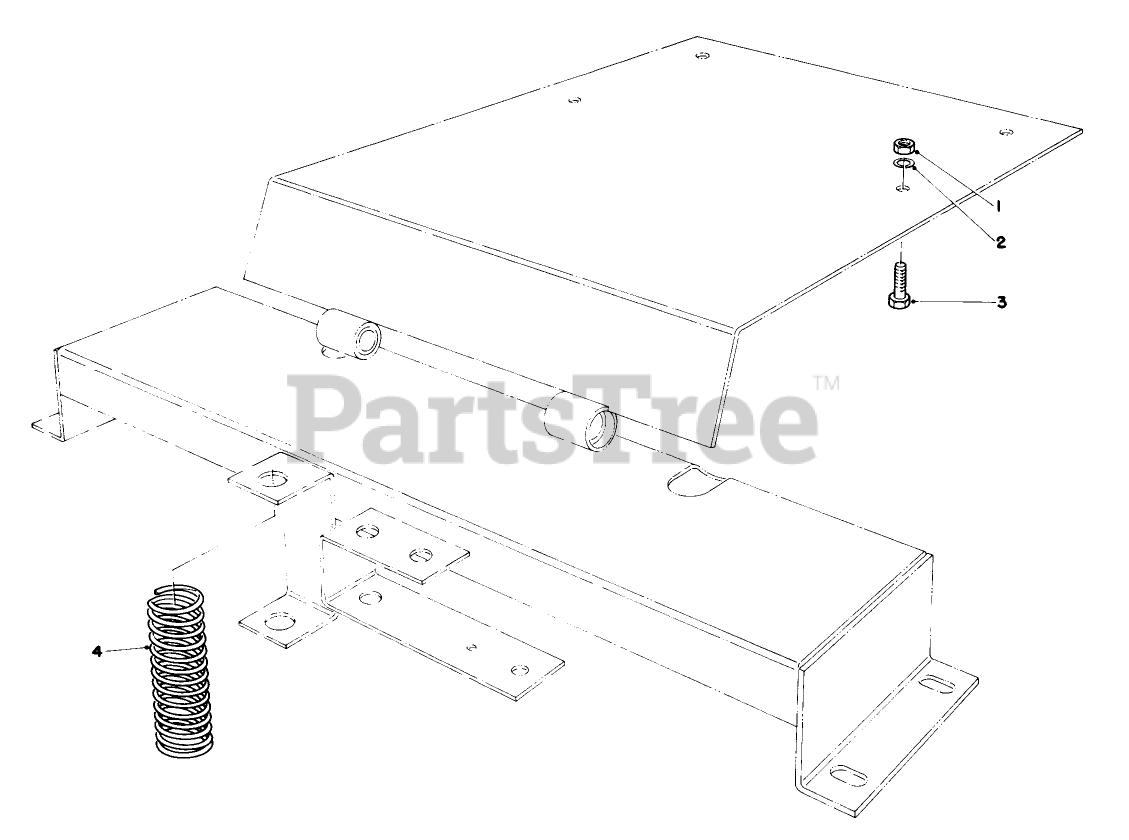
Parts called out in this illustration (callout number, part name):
1	NUT-HEX
2	WASHER-LOCK/SP
3	SCREW-HH
